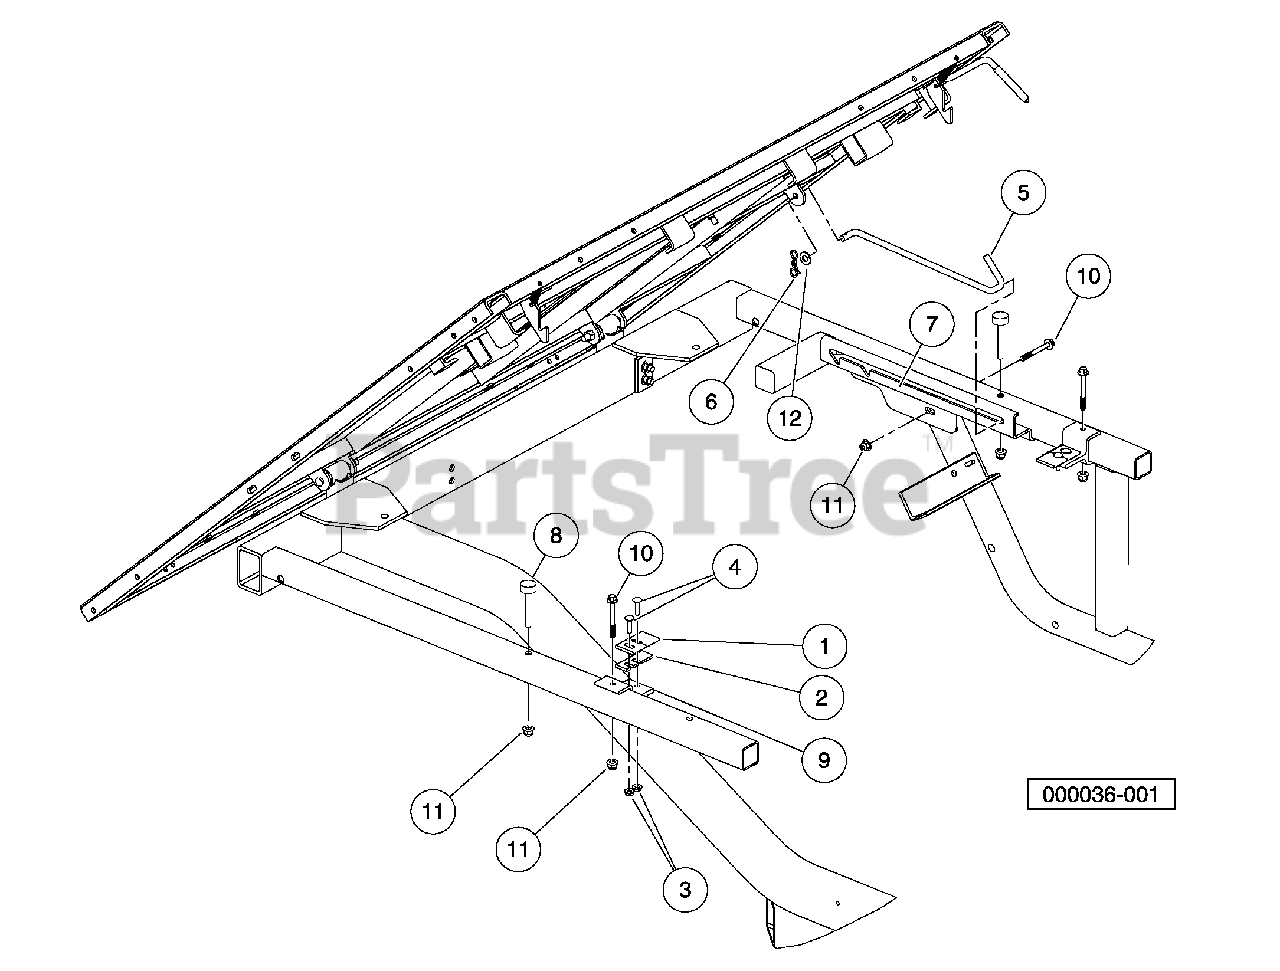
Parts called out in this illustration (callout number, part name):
1	Latch Plate, Tilt Bed
2	Latch Plate Shim
3	Locknut, 1/4-20 Hex Whiz
4	Bolt, Carriage, 1/4-20 X 1.0
6	Pin, Bow Tie Locking
7	Track, Prop Rod
8	Bumper, Bed, Mtg, Front
9	Bracket, Latch, Bed
10	Bolt Flanged Head, M8 X 1.25 X 65
11	Lock Nut, Flg M8 X 1.25 Nylon
12	Washer, 3/8 Type A Flat
